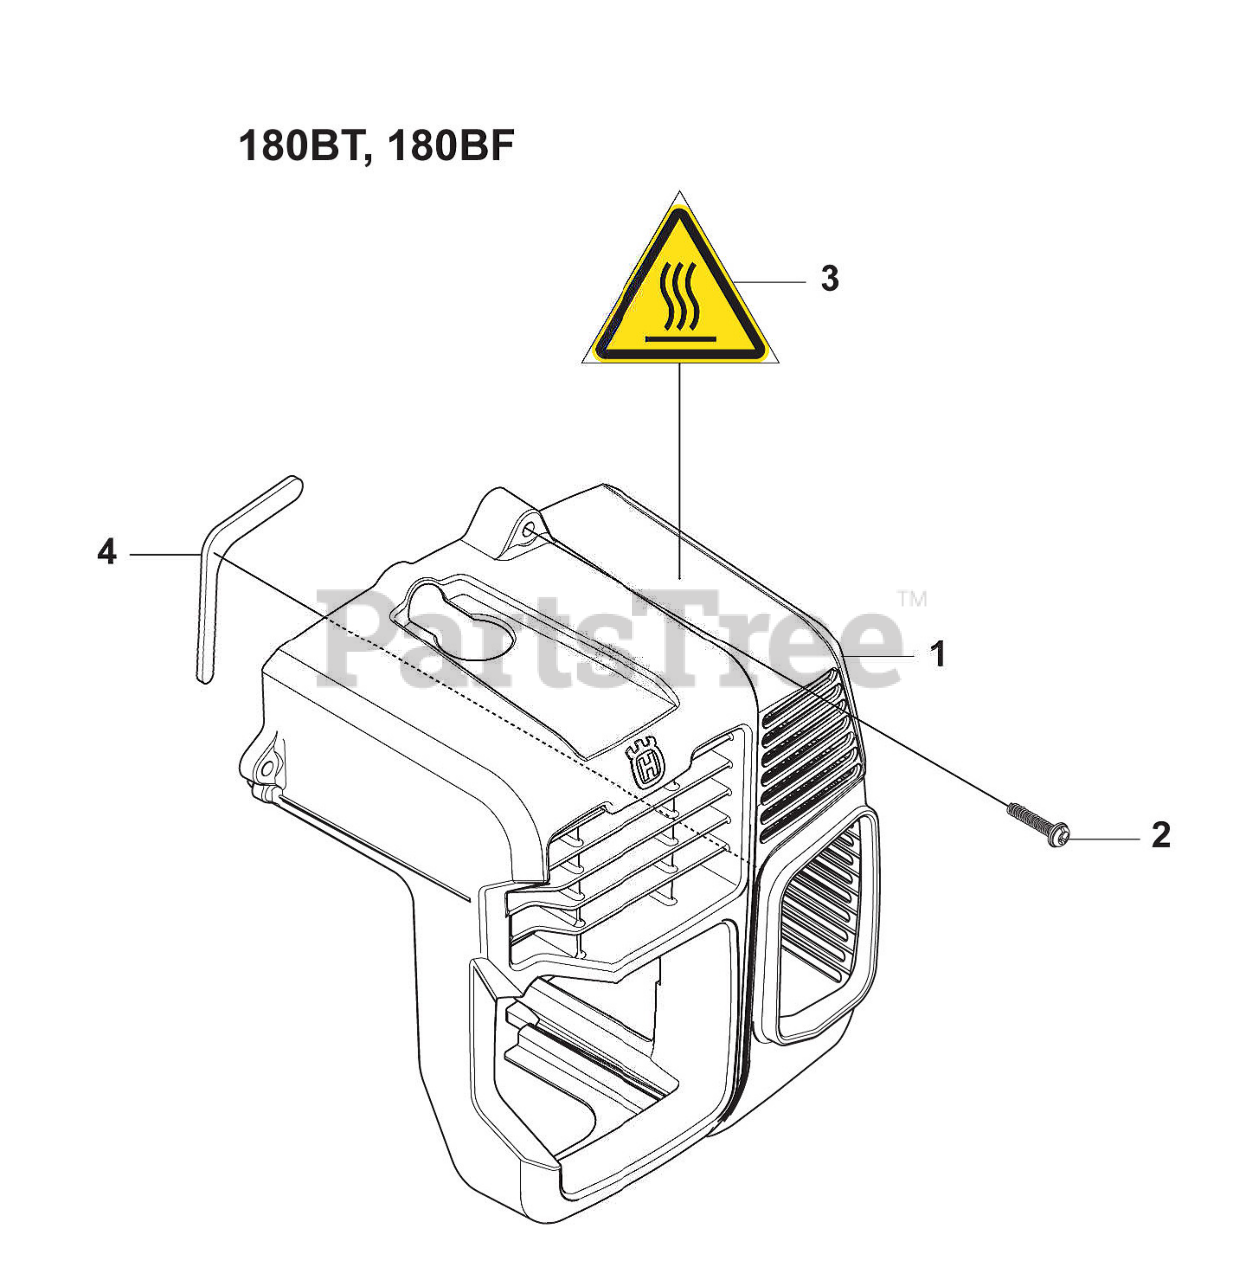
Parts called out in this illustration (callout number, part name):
1	Engine Cover
2	Screw
3	RP_LABEL, HOTMARK
